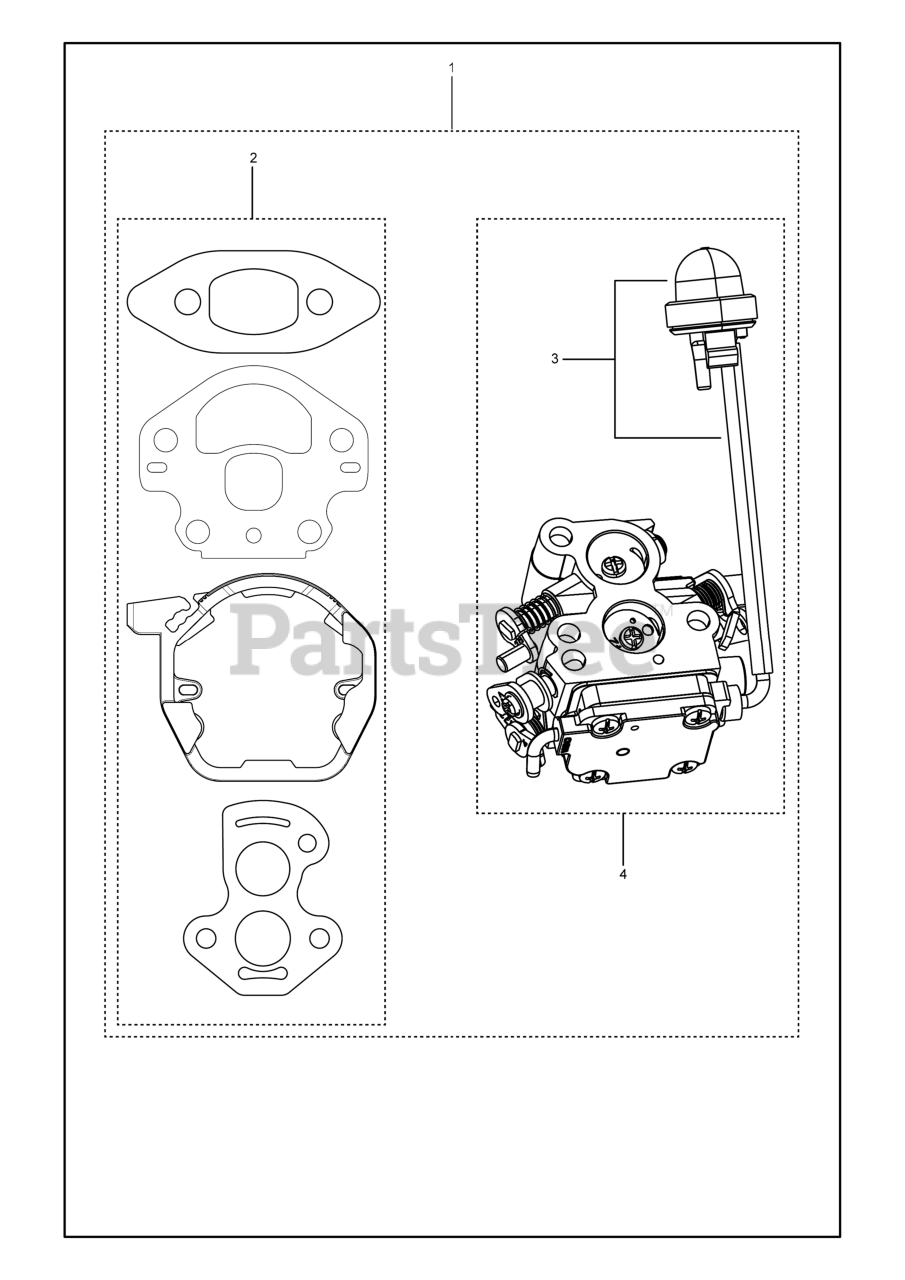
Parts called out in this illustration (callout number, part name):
1	KIT CARB REPAIR
2	GASKET
3	PURGE & LINE ASSY
4	CARBURETTOR 14MM AIR BORE, ANG
